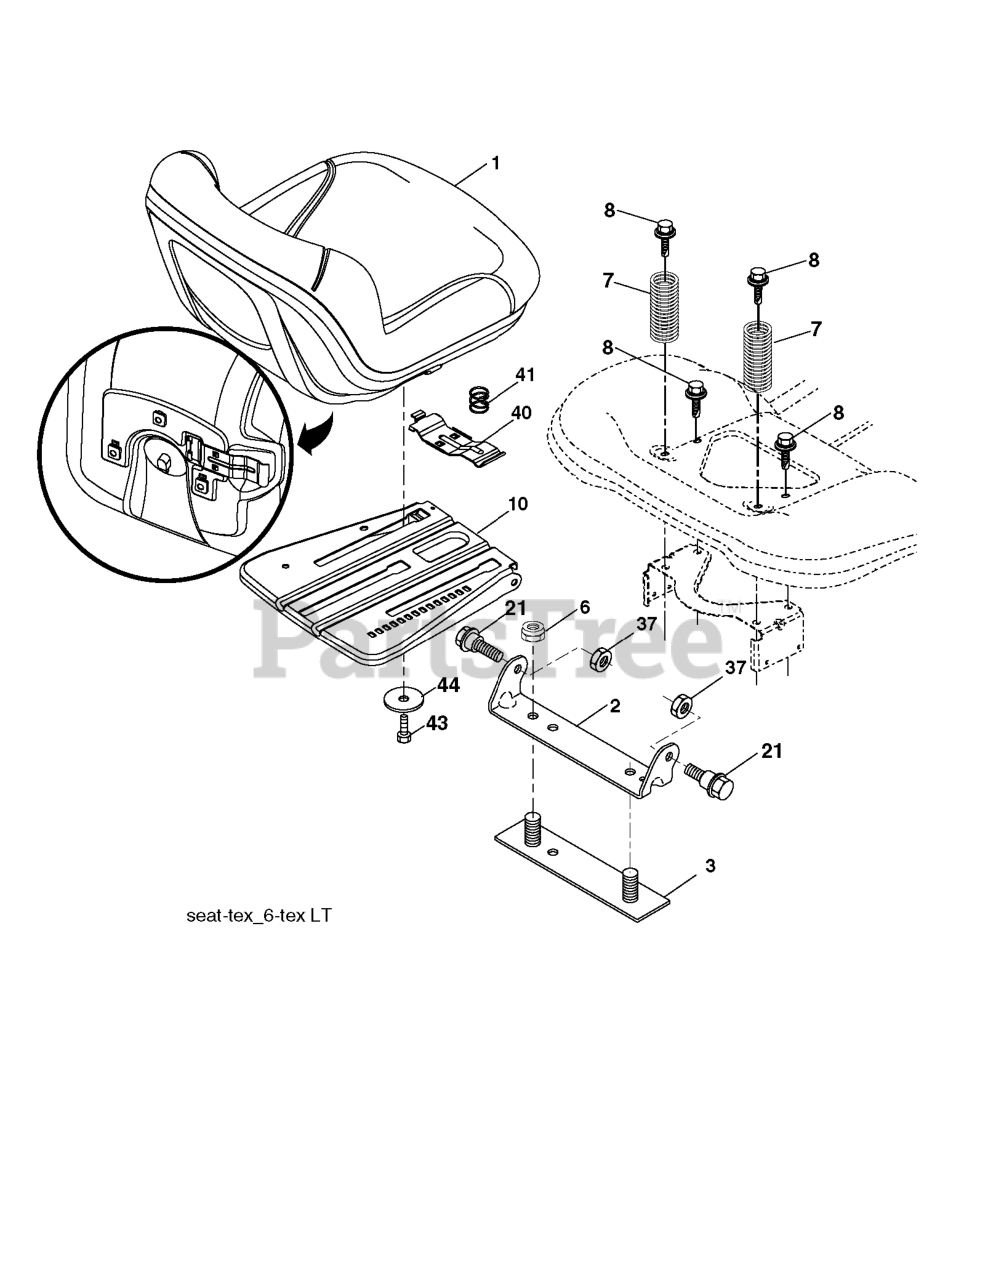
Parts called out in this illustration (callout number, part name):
1	RP SEAT.TH130.GRY.MILSCO.
2	BRKT.PIVOT.FENDER
3	STRAP
6	NUT
7	SPRING COMPRESSION
8	BOLT.5/16-18UNCX3/4 W/SEMS.BLK
10	PAN.ASM.SEAT.3PT
21	BOLT.SHOULDER.5/16-18
37	NUT.71038.31-18.HEX.NYLOCK
40	HANDLE.SLIDE.SEAT.TEX.BLACK
41	SPRING.LATCH.SEAT.TEX
44	WASHER 13/32 X 2-3/8 X 12GA
